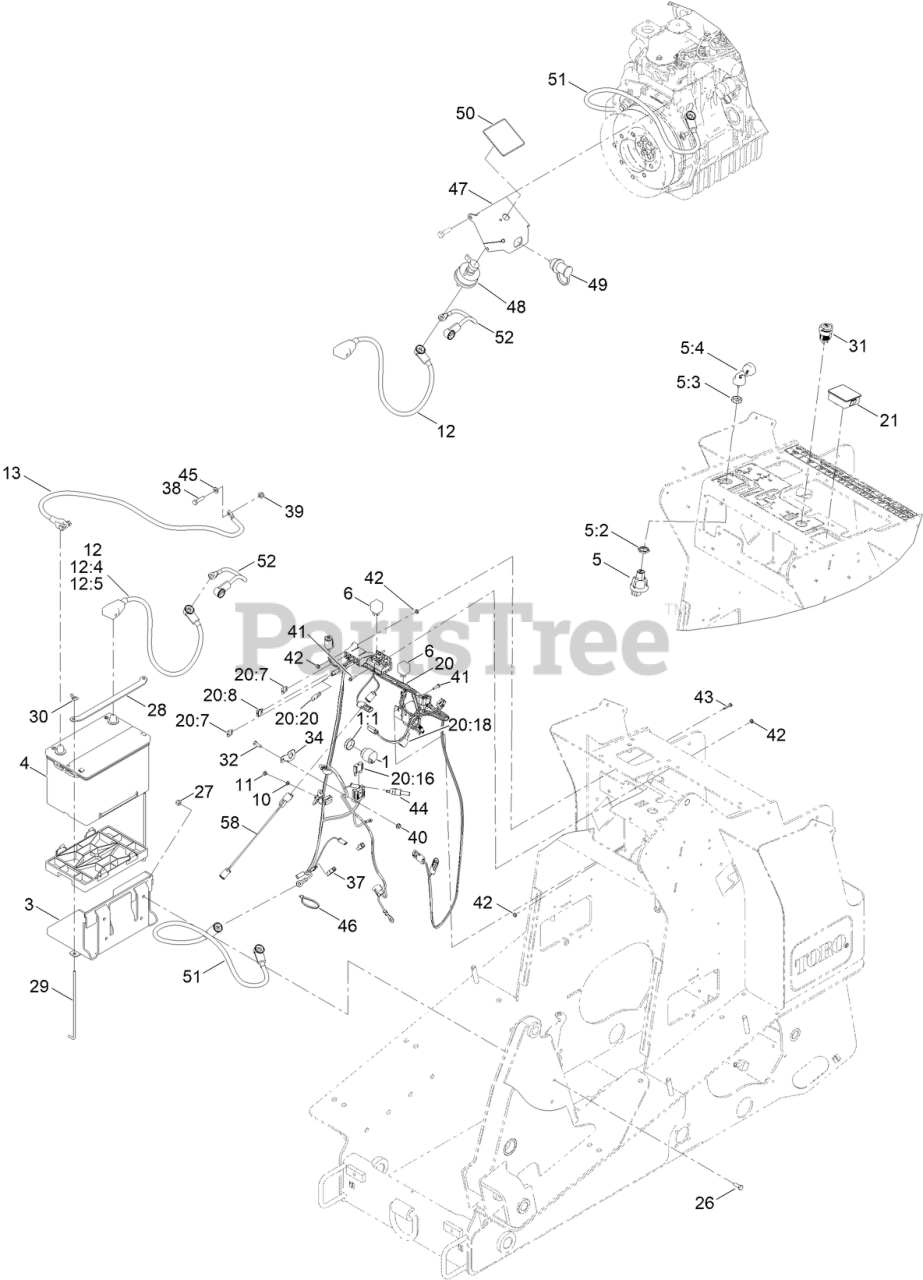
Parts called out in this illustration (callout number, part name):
1	AUDIO ALARM ASM
3	TRAY-BATTERY
4	BATTERY
5	IGNITION SWITCH ASM
5:2	NUT-HEX
5:3	NUT-FACE
5:4	SET-KEY, IGNITION
10	WASHER-LOCK, SPRING
11	NUT-HEX
12	CABLE-BATTERY, POS ASM
12:4	BOLT-BATTERY CLAMP, 5/16-18 UNC
12:5	NUT-CLAMP, BATTERY
13	CABLE-NEGATIVE
20	HARNESS-WIRE
20:7	FUSE-BLADE, 10 AMP
20:8	FUSE-BLADE, 15 AMP
20:16	FUSE-BLADE, 50 AMP
20:20	CAP-PLUG
21	MODULE-HOUR METER
26	SCREW-HH
27	NUT-LOCK, NI
28	STRAP-HOLD DOWN, BATTERY
29	ROD-HOLD DOWN, BATTERY
30	NUT-WING
31	RECEPTACLE-12V
32	SCREW-HH
34	CLIP-FUSE
37	HARNESS-LINK, FUSIBLE
38	SCREW-HH
39	NUT-HF, NI
40	NUT-HF
41	SCREW-HWH
42	NUT-KEPS
43	SCREW-HWHTF
44	SWITCH-TEMP
45	WASHER-PLAIN
46	TIE-CABLE
47	MOUNT-REMOTE TERMINAL
48	SWITCH-DISCONNECT, MASTER
49	STUD-JUMPER, POSITIVE
50	DECAL-BATTERY DISCONNECT
51	CABLE-BATTERY, POSITIVE
52	CABLE-BATTERY, POSITIVE
58	HARNESS-WIRE
